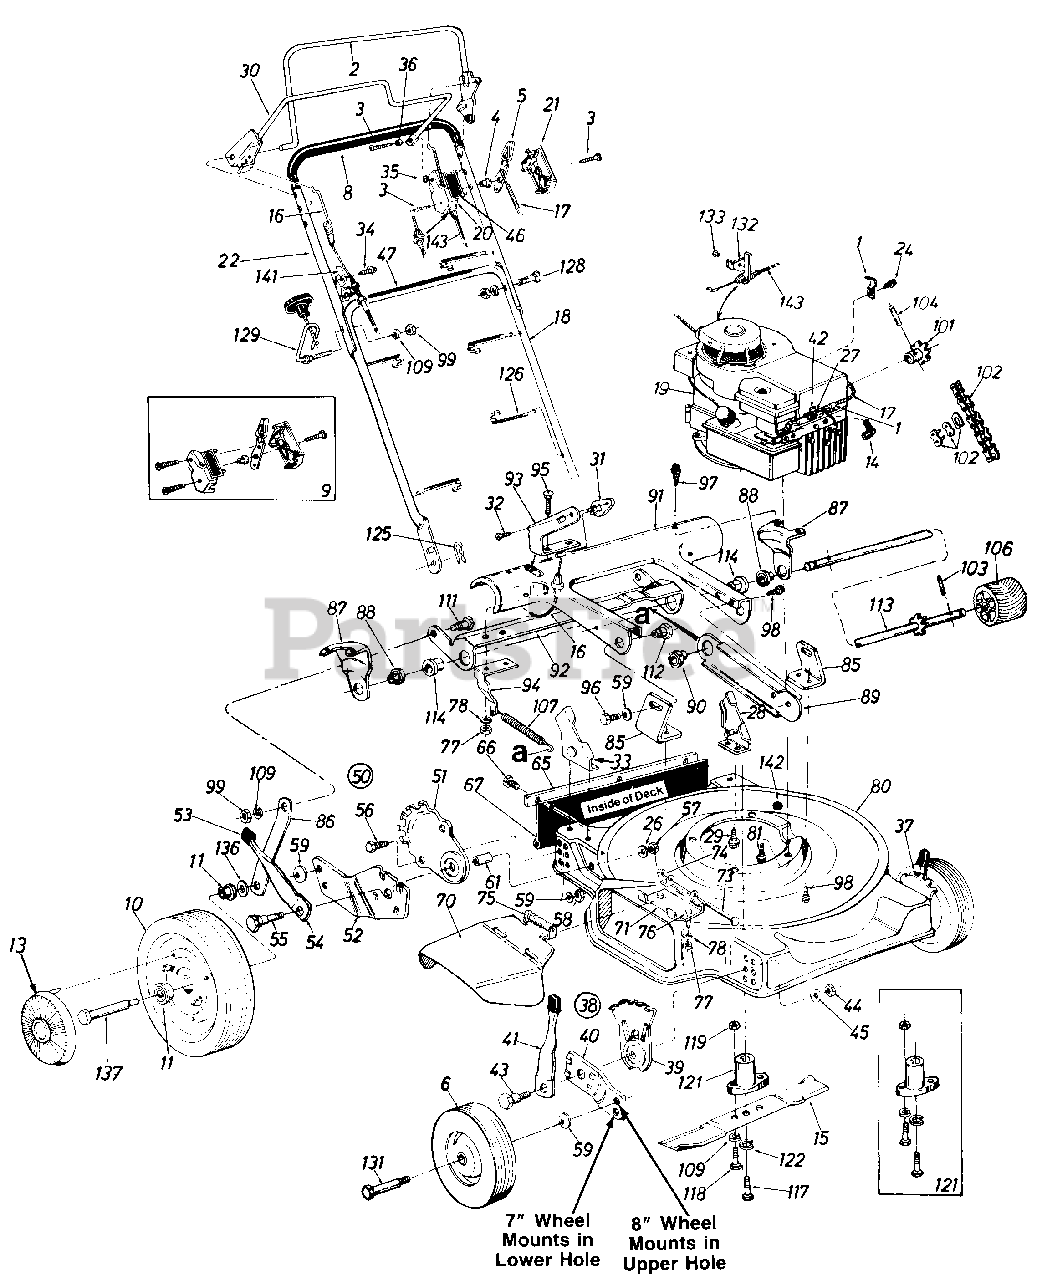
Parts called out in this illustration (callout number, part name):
1	Casing Clamp
2	Control Handle Ass'y. L.H.
3	Truss Mach. Hi-B Tap Scr. #12 x 1.5"
4	Control Disc Pin
5	Throttle Control Lever
6	Front Wheel Ass'y. Comp.
8	Grip
9	Control Housing Comp.
10	Rear Wheel Ass'y. Comp.
11	Fl. Ball Brg. 1/2" I.D.
14	Spark Plug Insulator
15	22" Blade
16	Clutch Cable w/Spring-33"
17	Throttle Wire 53"
18	Lower Handle
19	Engine
20	Clutch Panel Half
21	Control Panel Half
22	Upper Handle
24	Hex B-Tap Scr. #10 x .38"
26	Bell-Wash. 5/16" I.D.
27	Hex "B"-Tap Scr. #10 x .38"
28	Handle Brkt. Ass'y L.H.
29	Hex B-Tap Scr. 5/16-18 x .5"
30	S.P. Bail Ass'y.
31	Barrel Cable Hold-Down R.H.
32	B-Tap Scr. #10 x .38 Lg.
33	Handle Brkt. Ass'y R.H.
34	Hex Wash. AB-Tap Scr. 5/16 x .75"
35	Spr-Wash. .206 I.D. x .448
36	Spacer .23 I.D. x .30 O.D.
37	Front Height Adj. Ass'y. L.H.
38	Front Height Adj. Ass'y. R.H.
39	Height Adj. Plate
40	Pivot Bar
41	Spring Lever Ass'y. w/Knob
42	Casing Clamp
43	Shld. Bolt .50 Dia. x .430
44	Hex Nut 3/8-16 Thd.
45	Bell-Wash. .39 I.D. x 1.38 O.D.
46	Control Label
47	Instruction Label
50	Rear Height Adj. Ass'y. R.H.
51	Index Plate
52	Pivot Bar R.H.
53	Spring Lever Knob
54	Spring Lever
55	Shld. Bolt .50 Dia. x .433
56	Hex Bolt 3/8-16 x .75
57	Hex Cent. L-Nut 5/16-18 Thd.
58	Hex Nut 3/8-16 Thd.
59	Bell-Wash. .40 I.D. x .88 O.D.
61	Spacer .383 I.D. x .503 O.D.
65	Retaining Strip
66	Hex AB-Tap Scr. 1/4 x .62
67	Rear Flap Ass'y.
70	Chute Deflector Ass'y.
71	Adapter Plate
74	Push Nut 1/4"
75	Torsion Spring
76	Hex Bolt 1/4-20 x .50 Lg.
77	Hex Nut 1/4-20 Thd.
78	L-Wash. 1/4 I.D.
80	22" Deck Ass'y.
81	Hex TT-Tap Scr. 3/8-16 x 1.0
85	Pivot Brkt.
87	Axle Brkt.
88	Fl. Ball Brg. 1/2" I.D.
89	Brg. Support
90	Fl. Ball Brg. 1/2" I.D.
91	Pinion-Pivot Cover
92	Drive Engagement Cam
93	Engagement Arm L.H.
94	Spring Bracket
95	Carriage Bolt 1/4-20 x .62
96	Hex Bolt 3/8-16 x .50 Lg.
97	Hex AB-Tap Scr. 1/4 x .62
98	Hex AB-Tap 1/4 x .62"
99	Hex Nut 5/16-18 Thd.
101	10T Sprocket Ass'y.
102	#48 Chain 1/2a Pitch 50 Links
103	Spring Pin Spir. 3/16 Dia. x 1.25
104	Spring Pin Spir. 3/16 Dia. x 1.0
106	Drive Pinion
107	Extension Spring 4.25 Lg.
109	L-Wash. 5/16 I.D.
111	Shld. Bolt .437 Dia. x .162
112	Shld. Nut .625 Dia. x .165
113	Pinion Shaft w/7T Sprocket
114	Fl. Ball Brg. .501 I.D.
117	Hex Bolt 3/8-24 x 2.25
118	Hex Bolt 5/16-24 x 1.0 Spec.
119	Hex Nut 5/16-24 Thd.
121	Blade Adapter Kit
122	L-Wash. 3/8 I.D. H.D.
125	Intern. Cot. Pin 5/16 Dia.
126	Cable Tie
128	Curved Carriage Bolt 5/16-18 x 1.38" Lg.
129	Rope Guide Bolt
131	Front Axle Bolt
132	Cable Bracket
133	Pop Rivet .156" Dia. x .379
136	Fl-Wash. .531 I.D. x .93 O.D.
137	Rear Axle Bolt
141	Cable Brkt.
142	Plastic Plug
143	Control Cable 39" (Green)
8222-000-7	Hardware Pack
